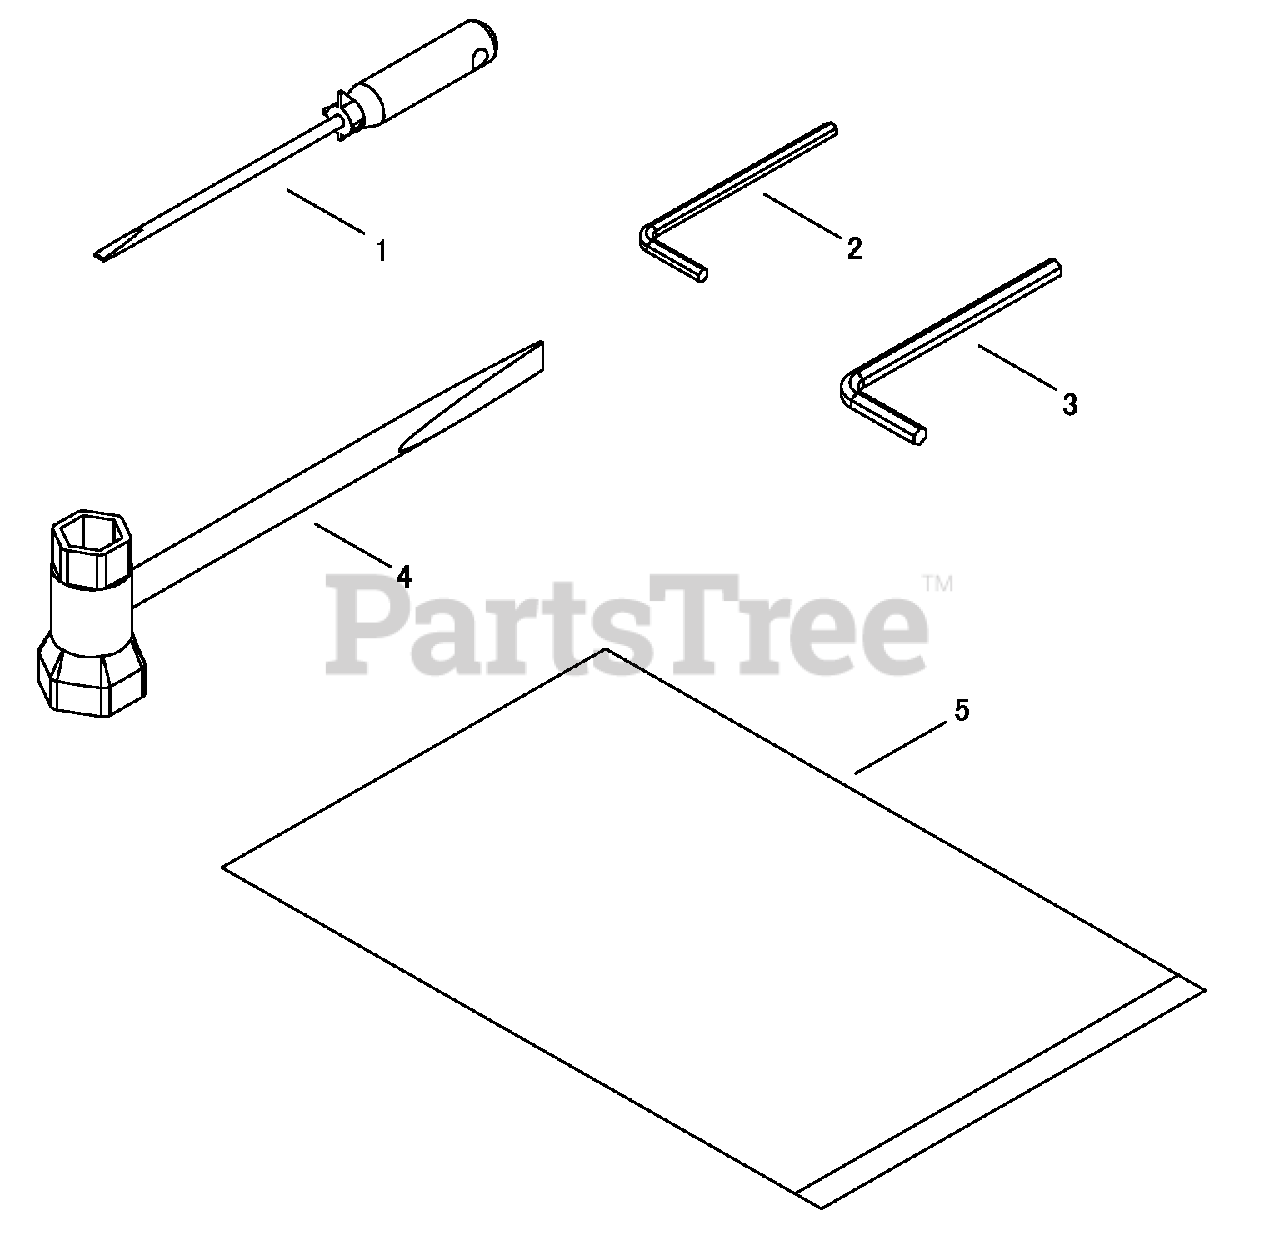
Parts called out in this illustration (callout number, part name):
1	SCREWDRIVER
2	WRENCH, ALLEN 3 MM
3	WRENCH, ALLEN 4 MM
4	T-WRENCH 13×19 MM
5	BAG, TOOL
